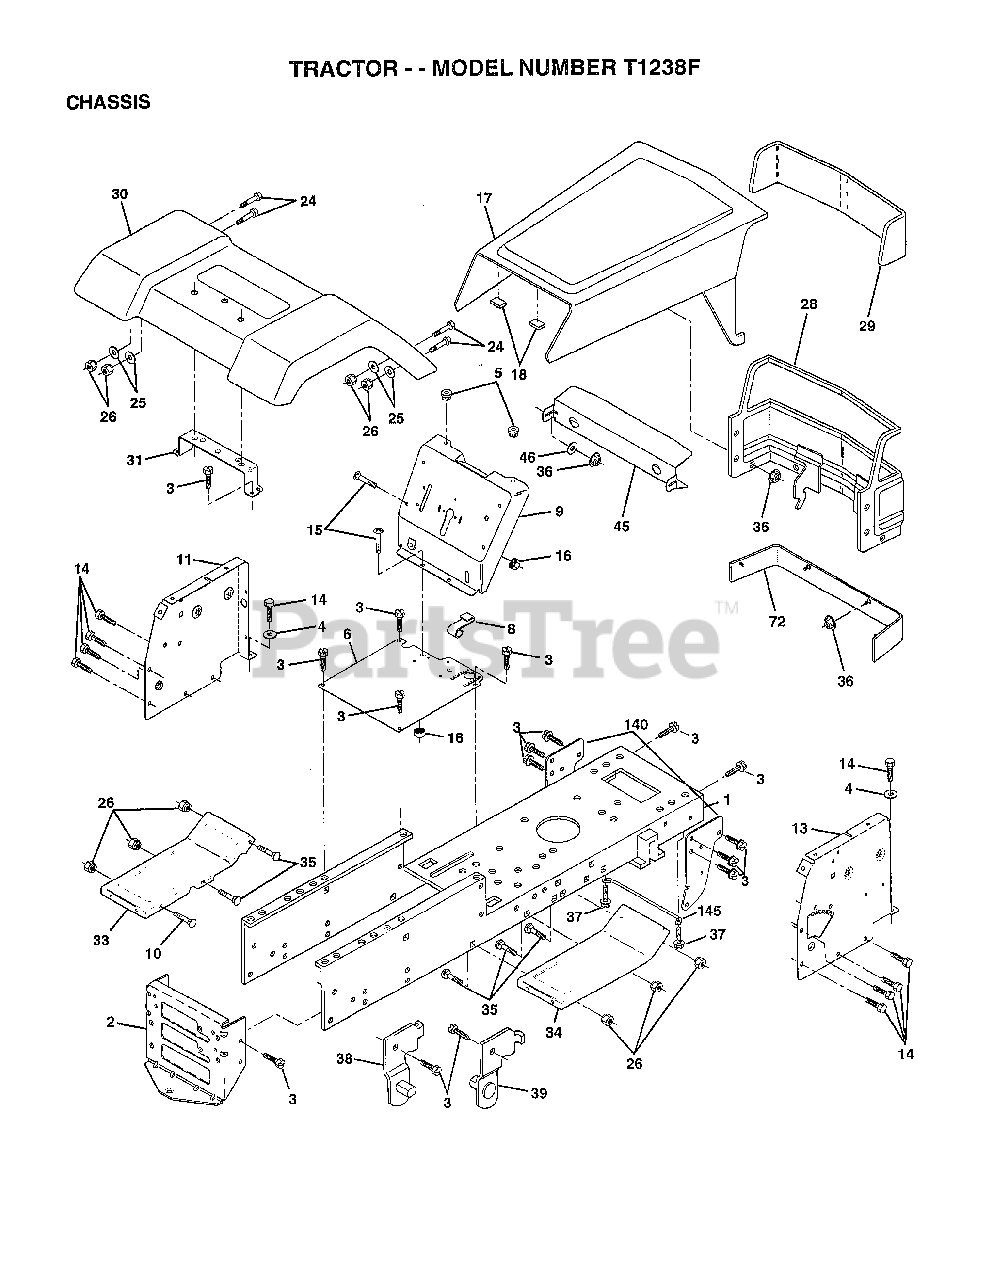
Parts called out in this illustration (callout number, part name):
3	SCREW
4	WASHER
5	BUMPER-HOOD/DASH
6	SADDLE-SILKSCREEN
8	CLIP.RETAINER
9	DASH.SILKSCREEN
11	"PANEL-DASH,LH"
14	SCREW LT
15	SCREW
17	HOOD.W/SD.PNLS.LT
24	BOLT
25	WASHER
26	NUT
28	GRILLE.RALLY.BAR.
29	LENS SERVICE KIT
30	FENDER PNT LT
31	BRKT FENDER
33	FOOTREST.LH.PERF.
34	FOOTREST.RH.PERF.
35	BOLT
36	PAL NUT LT
38	BRACKET ASM LH
39	BRACKET ASM RH
46	RETAINER
140	BRKT SUSPENSION
145	"ROD POVOT,CHASSIS"
